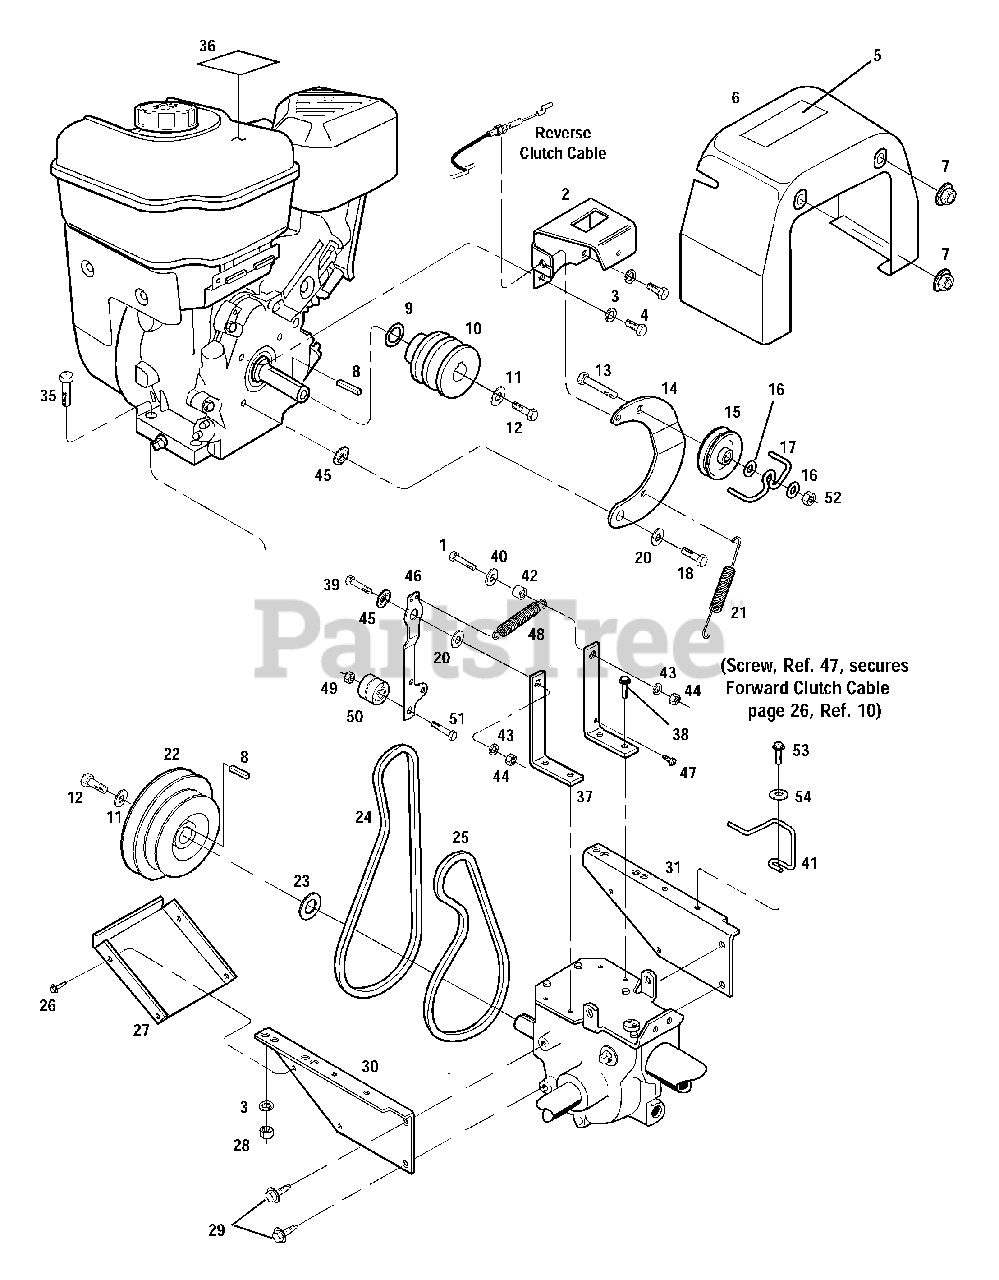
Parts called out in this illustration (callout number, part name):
1	Hex Hd. Screw, 5/16-18 x 2-1/4
2	Bracket, Clutch Cable
3	Lockwasher-5/16
4	Hex Hd. Screw, 5/16-24 x 1/2
5	Decal, Hot Surfaces / Belt Warning
6	Cover
7	Flange Lock Nut, 5/16-18
8	Key, 3/16 x 1-1/2
9	Shim, 1.0 x .7656 x .062
10	Pulley, Engine Drive
11	Washer, .827 x .331 x .098
12	Hex Hd. Screw, 5/16-24 x 1-1/8
13	Hex Hd. Screw, 5/16-18 x 2
14	Reverse Idler Arm
15	Pulley, Reverse Idler
16	Flat Washer, 5/16
17	Belt Guide, Wire Formed
18	Hex Head Screw, 5/ 16-24 x 1
19	Washer, Shoulder
20	Washer, Flat, 1-1/8
21	Spring, Reverse Return
22	Transmission Pulley
23	Support Washer
24	Reverse Clutch Belt
25	Forward Clutch Belt
26	Self-tapping Screw, #10-32 x 1/2
27	Guard, Belts/Pulleys
28	Hex Nut, 5/ 16-18
29	Hex Flange Screw, 5/16-18 x 3/4
30	Engine Support Bracket, left side
31	Engine Support Bracket, right side
35	Hex Hd. Screw, 5/16-18 x 1-1/2
36	Decal, Stabilization
37	Mounting Bar
38	Hex Flange Screw, 5/16-18 x .75
39	Hex Hd. Screw, 5/16-18 x 2-1/4
40	Flat Washer, 5/16'
41	Belt Guide, Pony
42	Pivot Bushing
43	Lockwasher, 5/ 16
44	Hex Nut, 5/ 16-18
45	Washer, Shoulder
46	Idler Arm, Forward Tiller Direction
47	Screw, self tapping, #10-24
48	Spring
49	Hex Locknut, 5/ 16-18
50	Idler Pulley, Forward
51	Screw, 3/8-16 x 1-3/4
52	Hex Lock Nut, 5/16-18
53	Screw, 1/4-20 x 3/4
54	Flat Washer, 1/4
